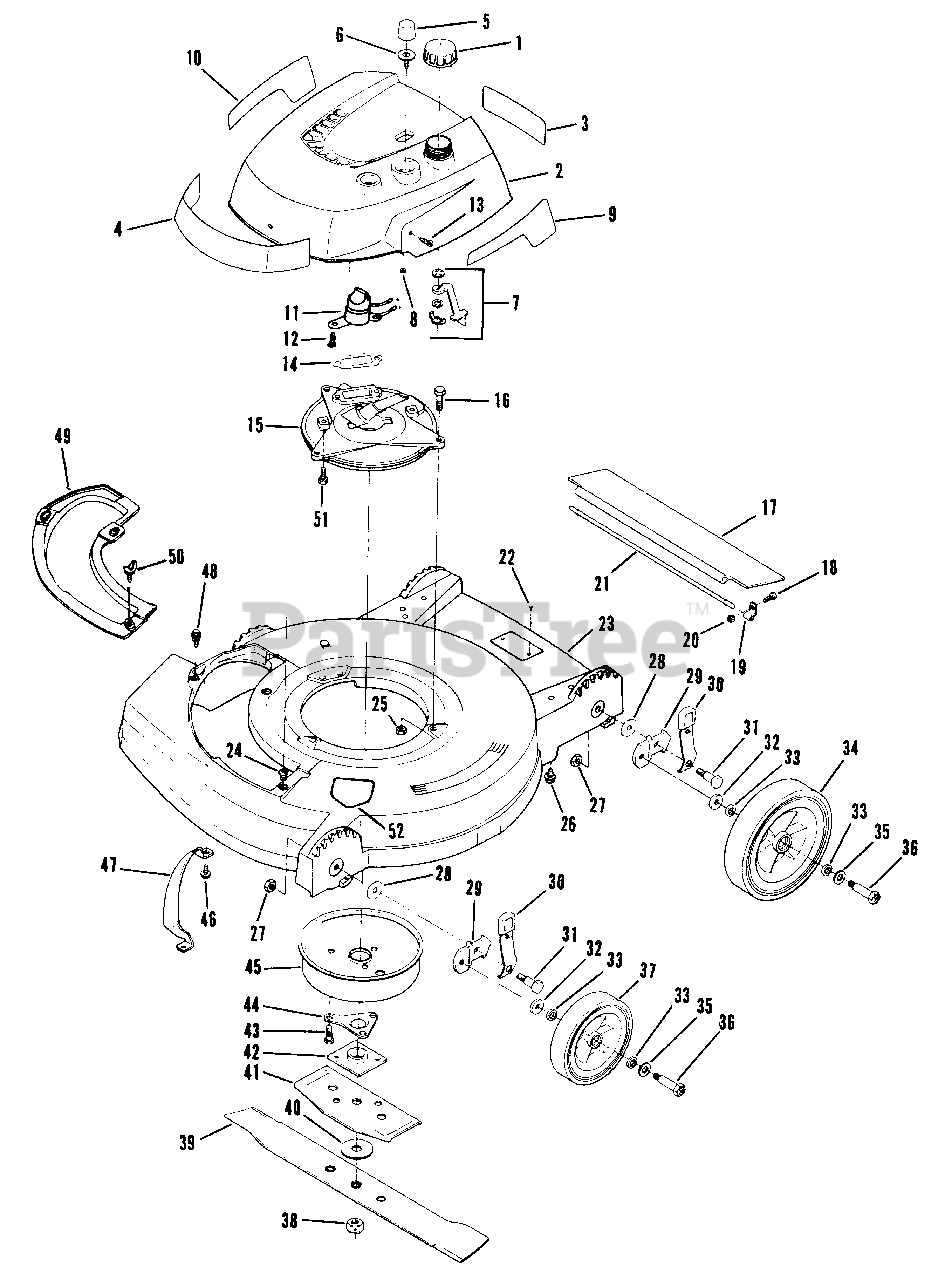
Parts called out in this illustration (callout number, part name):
1	Fuel Cap
2	Shroud-Engine
3	Decal-Instructions
4	Decal-Lawn-Boy
5	Bulb-Primer
6	Base-Primer
7	Fuel Shut-Off Assembly
8	Nut
9	Decal-L.H.
10	Decal-R.H.
11	Switch-On-Off
12	Screw
13	Screw-Shroud Mounting
14	Gasket-Exhaust
15	Plate-Muffler
16	Screw-Muffler Plate to Housing
17	Shield-Trailing 19"
17	Shield-Trailing 21"
18	Screw
19	Clamp
20	Nut
21	Rod-Trailing Shield 19"
21	Rod-Trailing Shield 21"
22	Screw-Model Plate Mounting
23	Housing-19"
23	Housing-21"
24	Grommet
25	Nut-Muffler Plate to Housing
26	Screw-Handle Bracket to Housing
27	Nut
28	Washer
29	Bracket-Wheel Height Adjustment
30	Knob & Spring Assembly
31	Shoulder Bolt
32	Washer
33	Washer-Felt
34	Wheel-Rear
35	Washer
36	Bolt-Wheel
37	Wheel-Front
38	Nut-Blade
39	Blade-19"
39	Blade-21"
40	Washer-Blade
41	Stiffener-Blade
42	Collar & Plate Assembly
43	Screw
44	Support-Crankshaft
45	Muffler Cover Assembly
46	Screw
47	Toe Bar-19"
47	Toe Bar-21"
48	Screw-Plate & Chute Mounting
49	Cover Plate
50	Wing Screw
51	Screw-Muffler Plate to Block
52	Decal-Blade Contact Warning
